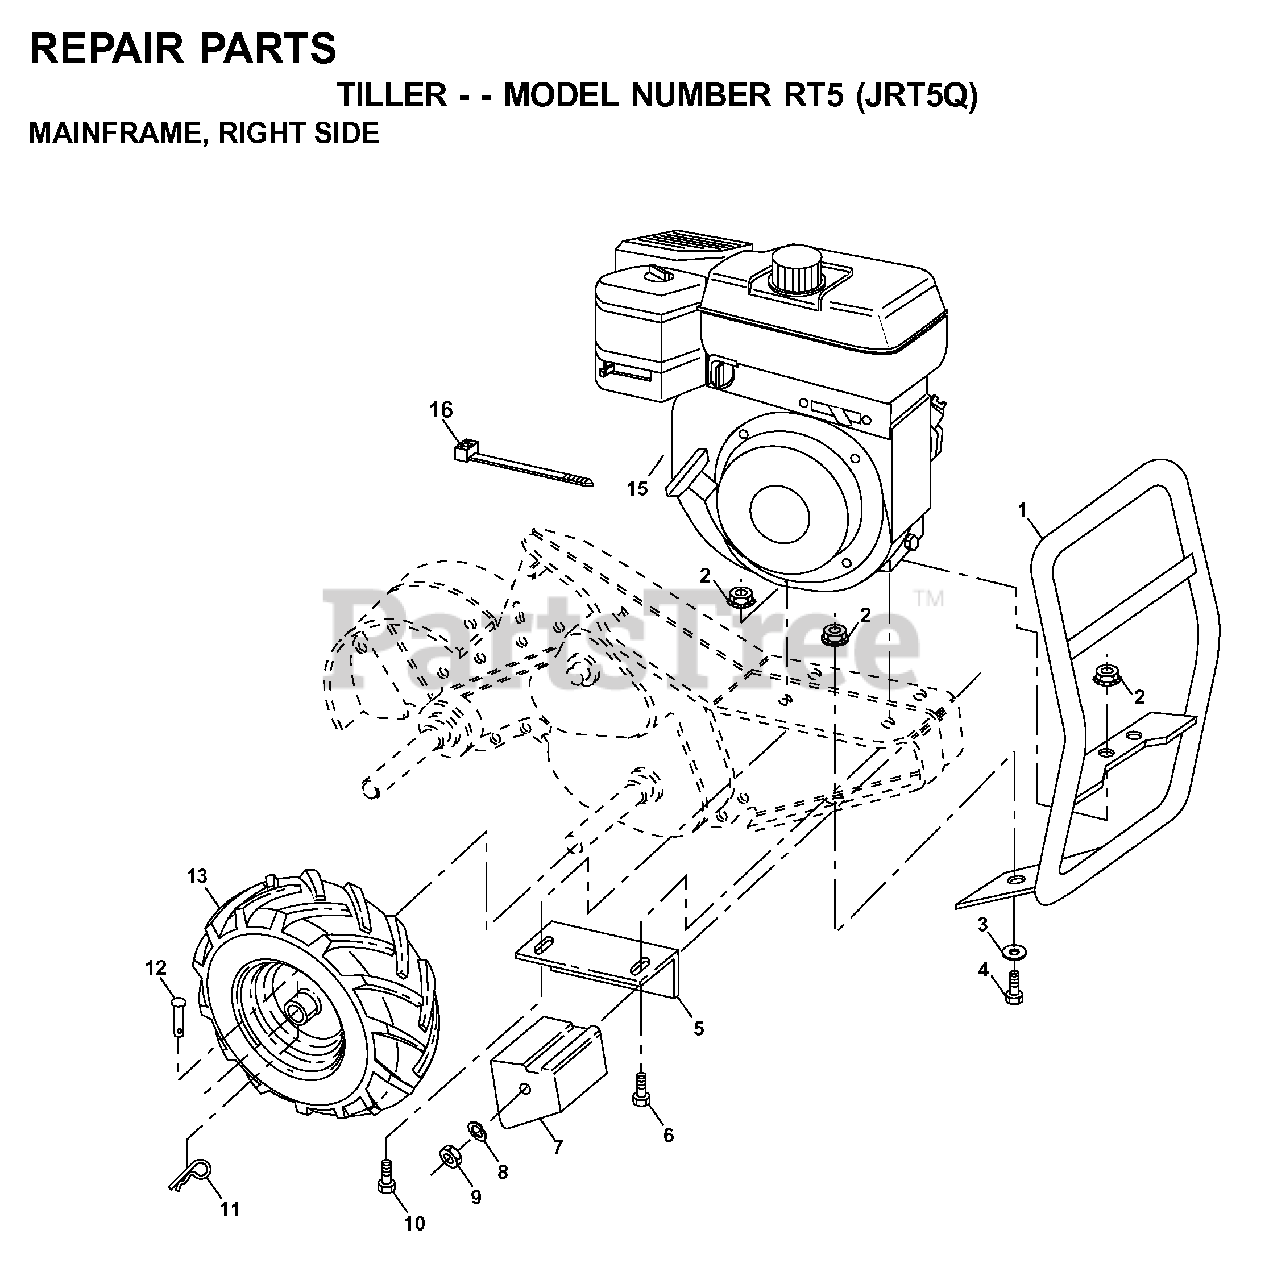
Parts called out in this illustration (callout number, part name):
1	BUMPER
2	LOCKNUT-FLANGE 5/16-18
3	WASHER
4	BOLT
5	BRACKET RH CRT
7	COUNTERWEIGHT, RH
8	WASHER, LOCK 3/8
9	NUT.HEX.3/8-16UNC
10	BOLT
11	RETAINER M
12	RIVET,DRILLED
16	TIE GUIDE
532124366	RIM
532124718	VALVE STEM LT
